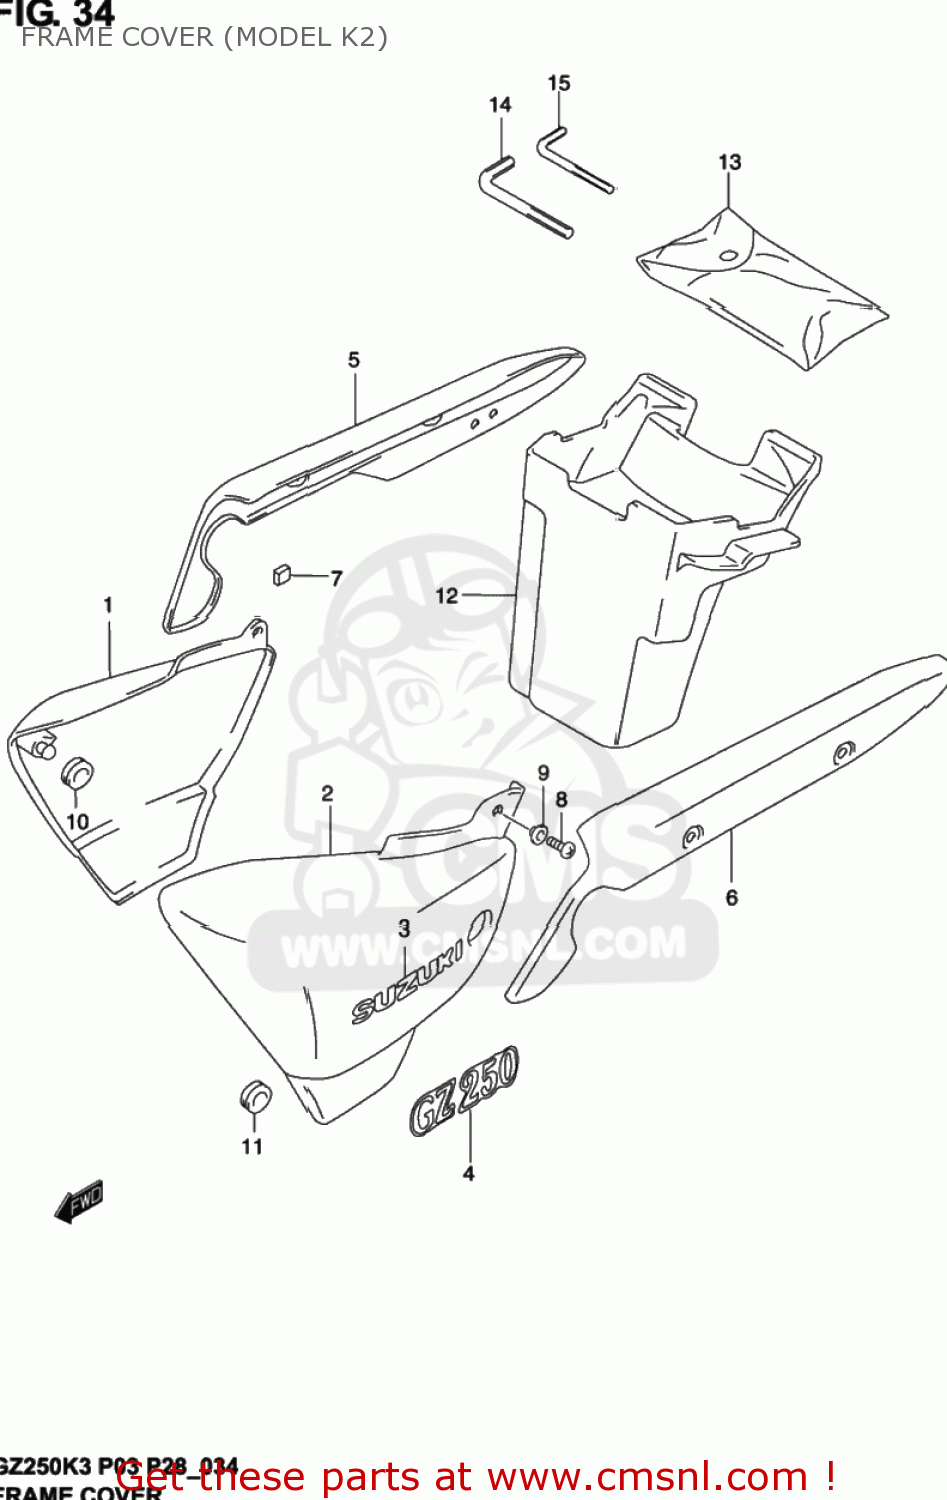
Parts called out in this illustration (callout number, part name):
1	COVER,FRAME,R(RED)
2	COVER,FRAME,L(RED)
3	EMBLEM, FRAME COVER
4	EMBLEM GZ125/K
5	COVER, FRAME REAR RH
6	COVER, FRAME REAR LH
7	CUSHION
8	SCREW 6X12
9	WASHER
10	CUSHION
11	CUSHION
12	BODY,LUGGAGE BOX
13	TOOL ASSY
14	SPANNER,HEXAGON(6)
15	SPANNER,HEXAGON(4)
